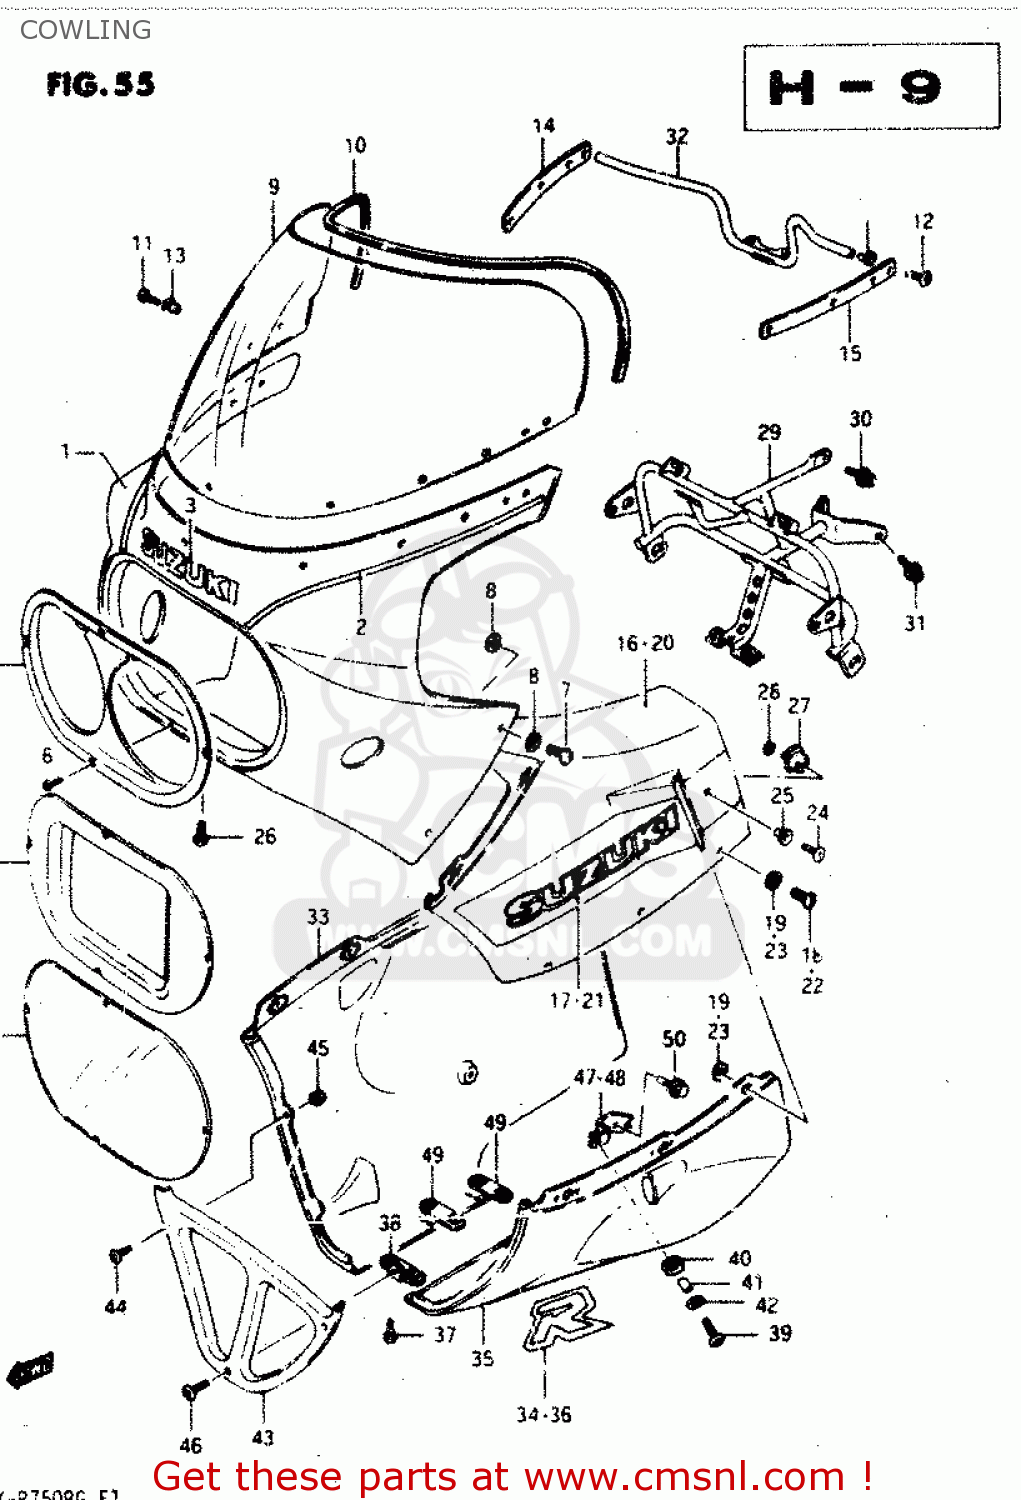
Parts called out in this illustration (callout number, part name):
1	BODY ASSEMBLY,COWLING SUB
2	TAPE SET,BODY COWLING STRIPE
3	EMBLEM,COVER SEAT TAIL
4	COVER,COWLING FR
5	COVER, FRONT (BLUE)
6	SCREW
7	FASTENER
8	WASHER,FASTENER
9	WINDSCREEN
10	MOLDING
11	SCREW(5X14)
12	SCREW(5X18)
13	NUT,COWLING SCREEN
14	PLATE,RR VIEW MIRROR,R
15	PLATE,RR VIEW MIRROR,L
16	COVER ASSEMBLY,COWLING
17	TAPE SET,SIDE COWLING,S,RIGHT
18	FASTENER
19	WASHER,FASTENER
20	COVER,COWLING SIDE,LEFT
21	TAPE SET,SIDE COWLING,S,LEFT
22	FASTENER
23	WASHER,FASTENER
24	SCREW(6X12)
25	WASHER
26	SCREW(6X16)
27	CUSHION,COWLING
28	WASHER,LOCK
29	BRACE,COWLING FR
30	BOLT
31	BOLT
32	BRACE,COWLING BODY RR
33	COVER,COWLING,LOWER,RIGHT
34	EMBLEM,COWLING,LOWER
35	COVER,COWLING,LOWER,LEFT
36	EMBLEM,COWLING,LOWER
37	SCREW(6X16)
38	BRACE,COWLING LWR COVER
39	SCREW(6X20)
40	CUSHION
41	SPACER
42	WASHER(6.5X18X1)
43	COVER,COWLING,LOWER,FRONT
44	SCREW(5X14)
45	NUT
46	SCREW(6X16)
47	BRACE,COWLING LWR,R
48	BRACE,COWLING LWR,L
49	BRACE,COWLING LWR COVER RR
50	BOLT
51	COVER,HEADLAMP
